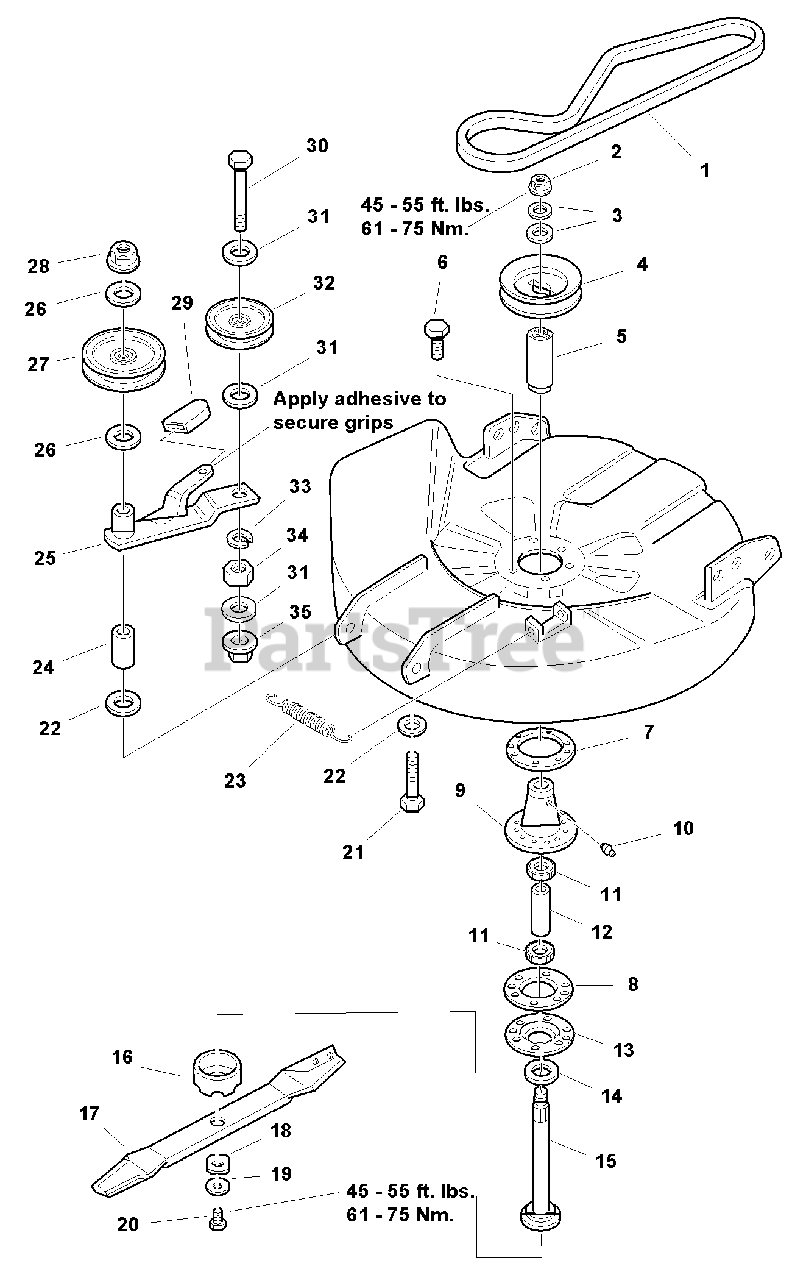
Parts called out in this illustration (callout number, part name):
1	V-BELT
2	NUT, Hex Flange, 9/16-18
3	WASHER, Belleville
5	HUB, Pulley, 1-3/16
6	CAPSCREW, Hex Head, Taptite, 5/16-18 x 1
7	ADAPTER, Arbor
8	GASKET, Foam
9	HOUSING ASSEMBLY, Arbor Bottom, w/Lube Fitting
10	FITTING, Grease
13	COVER, Arbor Housing
14	WASHER, Cupped
15	SHAFT, Arbor, 5-53/64"
16	SHIELD, Grass, Lower
17	BLADE, Mower, 30"
18	WASHER, Hex
19	WASHER, Spring
20	CAPSCREW, Hex Head, 7/16-14 x 1, GR 8
21	CAPSCREW, Hex Head, 3/8-16 x 3
22	WASHER, Flat, 3/8 x 1-1/2 x 1/8
25	LEVER ASSEMBLY
26	WASHER, Plain, 3/8
27	PULLEY ASSEMBLY Idler, Fixed, 6" Dia.
28	NUT, Hex, Whizlock, 3/8-16
29	GRIP, Lever
30	CAPSCREW, Hex Head, 3/8-16 x 2
31	WASHER, 13/32 x 1 x 1/8
32	IDLER PULLEY, Backside
33	LOCKWASHER, 3/8
34	NUT, Hex, 3/8
35	NUT, Hex, Lock, 3/8-16
